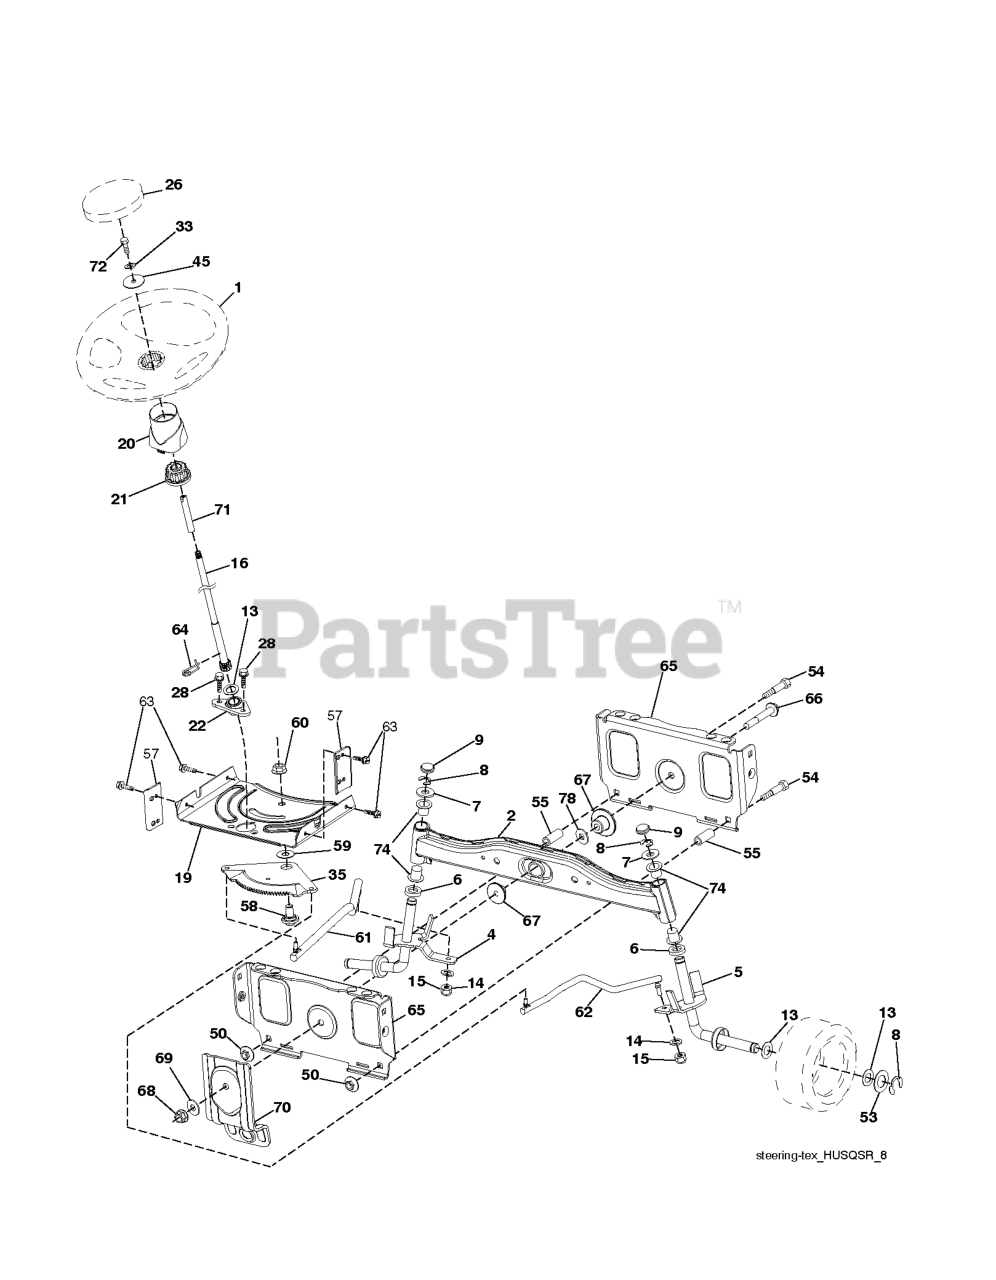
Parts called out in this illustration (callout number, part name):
1	RP WHEEL.STEER.HUSQ.PREM.OVMLD
2	AXLE HALF ASM-WELDED
4	SPINDLE.WELDED.LH.15"TEX
5	SPINDLE.WELDED.RH.15"T
6	THRUST WASHER
9	CAP.SPINDLE.BLACK
14	WASHER, LOCK 3/8
15	NUT CROWNLOCK 3/8-24
16	SHAFT STEERING
19	PLATE.STEER.DDL.NLT/NG
20	BOOT, STEERING
21	ADAPTER, WHEEL STNG..
22	BUSHING.ASM.STEERING.A
26	RP INSERT.CAP.WHL.STRG.HUSQ.
28	SCREW, 3/8-16X3/4
33	WASHER.LOCK.HVY.HLCL.SPR.5/16
35	GEAR.SECTOR.PLATE.DDL.
45	WASHER.11/32
50	NUT LOCK FLG 3/8-16 UNC
53	WASHER.HARDENED
55	SPACER.BRACE.AXLE
57	BRACKET.UPSTOP.TEX
58	BOLT.SHOULDER.SECTOR.P
59	WASHER.THURST.SECTOR.S
60	NUT FLANGE LOCK 5/8-11
61	DRAGLINK.LH.BALLSTUD.D
62	DRAGLINK.RH.BALLSTUD.D
63	SCREW
64	RETAINER.CLIP.SPRING.S
65	BRACE.AXLE.FRONT.NLT/N
66	BOLT HEX FGHD 7/16-14 X 3 SERR
67	BUSHING.PM.FRONT AXLE
68	NUT.LOCK.FLANGE.7/16
69	WASHER.1.5X.505X.118
70	BRKT.DECK.SUSPENSION.F
71	SHAFT EXTENSION STEERING
72	BOLT YT
74	BRNG T
78	THRUST WASHER
